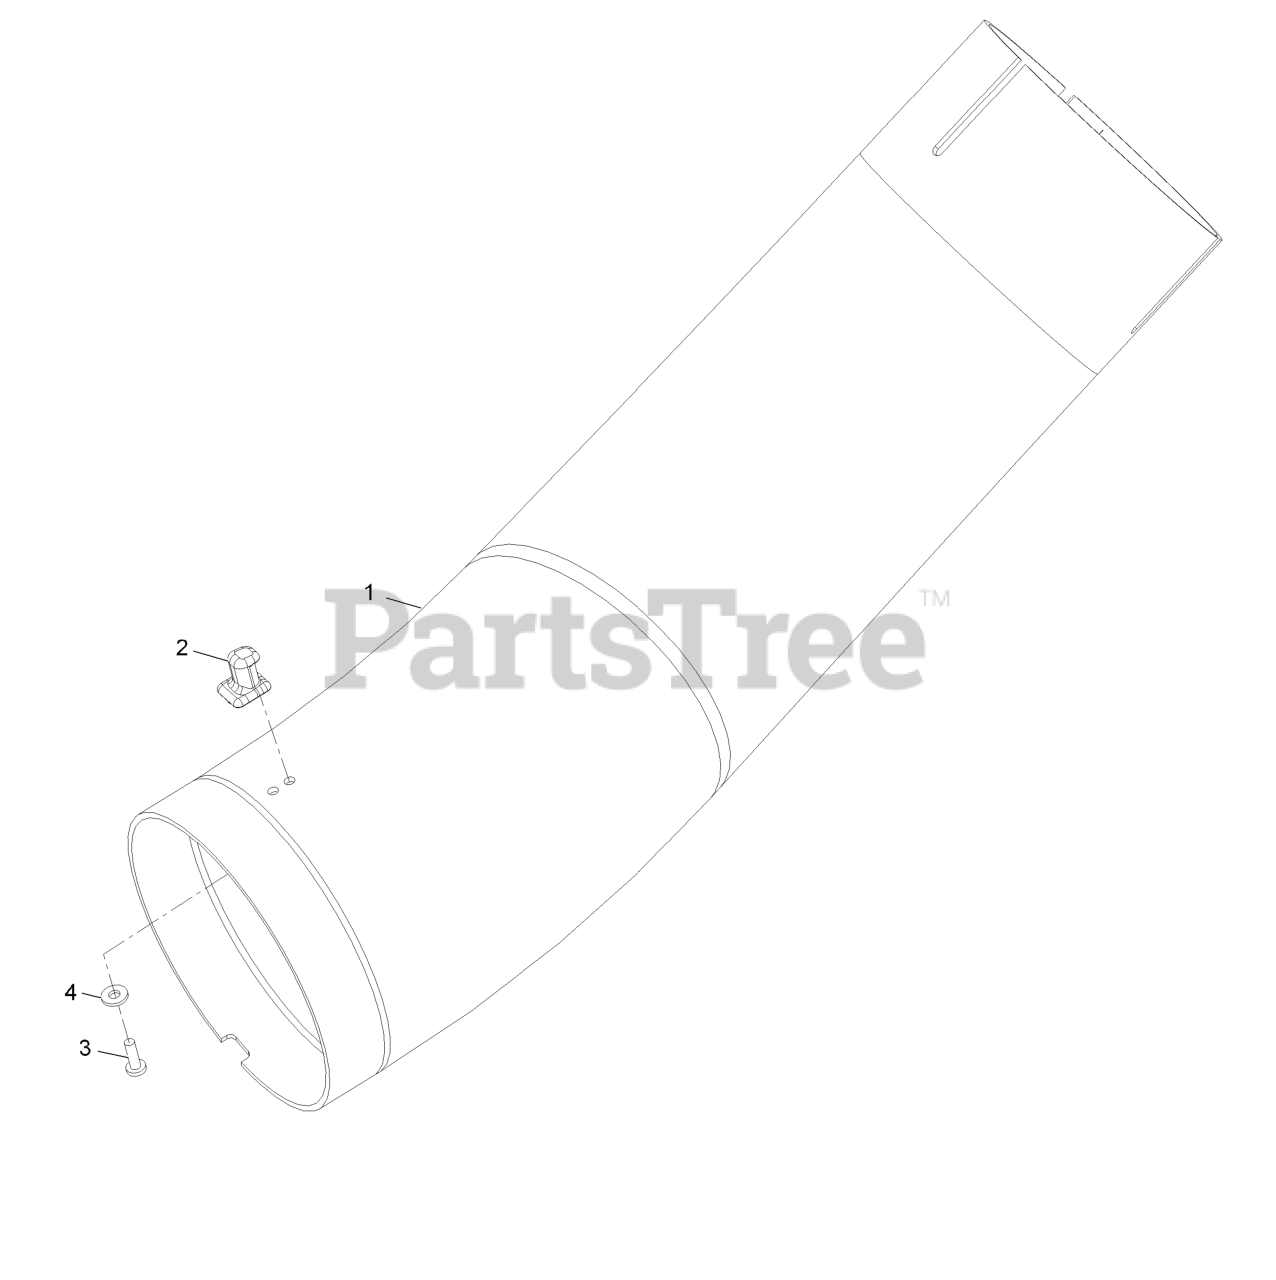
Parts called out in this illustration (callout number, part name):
1	Tube-Lower, Short
2	Latch-Keeper
3	Screw-PPH #10-24 X 5/8
4	Washer-#10 Std
